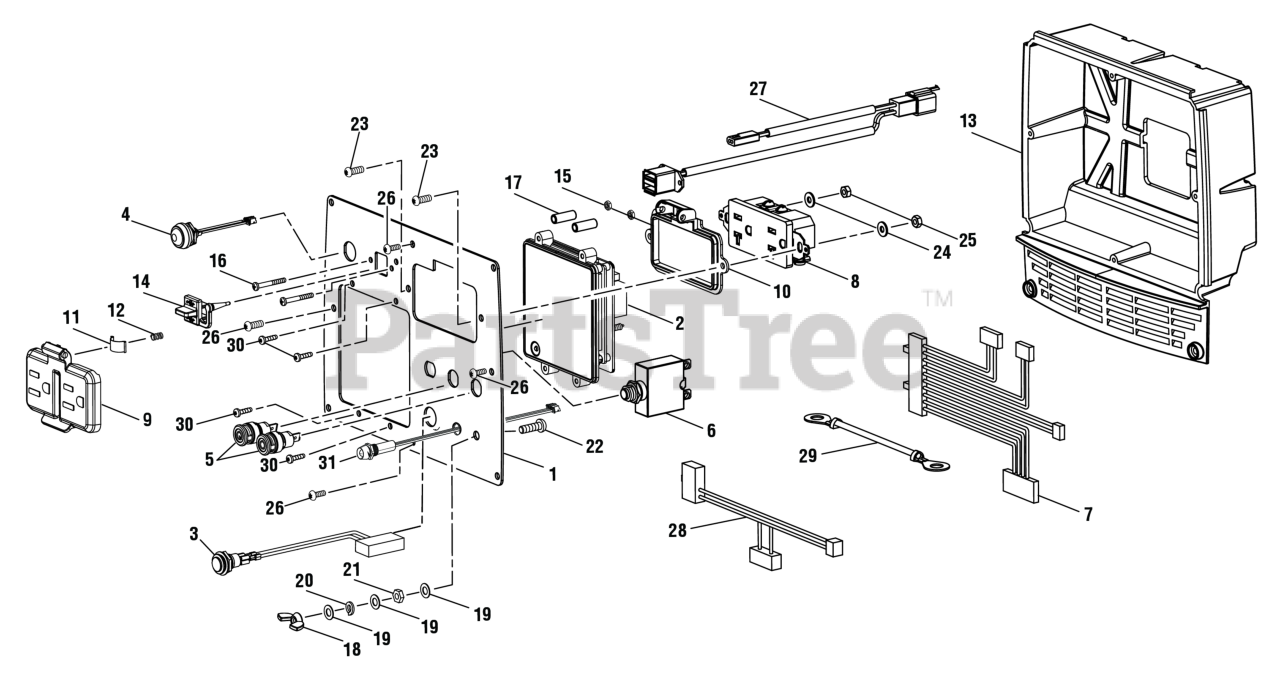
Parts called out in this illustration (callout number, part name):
1	Faceplate
2	GEN CONTROL DISPLAY ASSEMBLY RYi2300BTA
3	Overload Reset Button
4	Auto Idle Button
5	Connector (Black)
6	Circuit Breaker (20 Amp, 125 Volt)
7	Wire Harness (GENControl(TM) Display)
8	120 Volt Duplex Receptacle (BM903611)
9	Receptacle Cover (Front)
10	Fixed Outlet Cover
12	Governor Damping Spring
13	Electrical Panel Housing
14	Dual USB Cover
15	Hex Nut (M3)
16	Screw (M3 x 25 mm, Phillips Pan Hd )
17	Spacer (17.2 mm)
18	Wing Nut (M5)
19	Flat Washer (OD10 x ID5.3 x 0.5t)
20	Lock Washer (OD9 x ID5 x 1.3t)
21	Hex Nut (M5)
22	Screw (M5 x 16 mm, Phillips Pan Hd.)
23	Bolt (M4 x 10 mm, T15 Torx Drive Hd.)
24	Flat Washer (OD10 x 42 x 1t)
25	Flange Nut (M4)
26	Screw (#6-20 x 3/8 in., T15 Torx Pan Hd.)
27	Regulator Wire Harness w/ USB Ports
28	Internal Wire Assembly
29	Ground Wire
30	Screw (M3.1 x 10 mm, Torx pan Hd.)
31	CO Indicator
